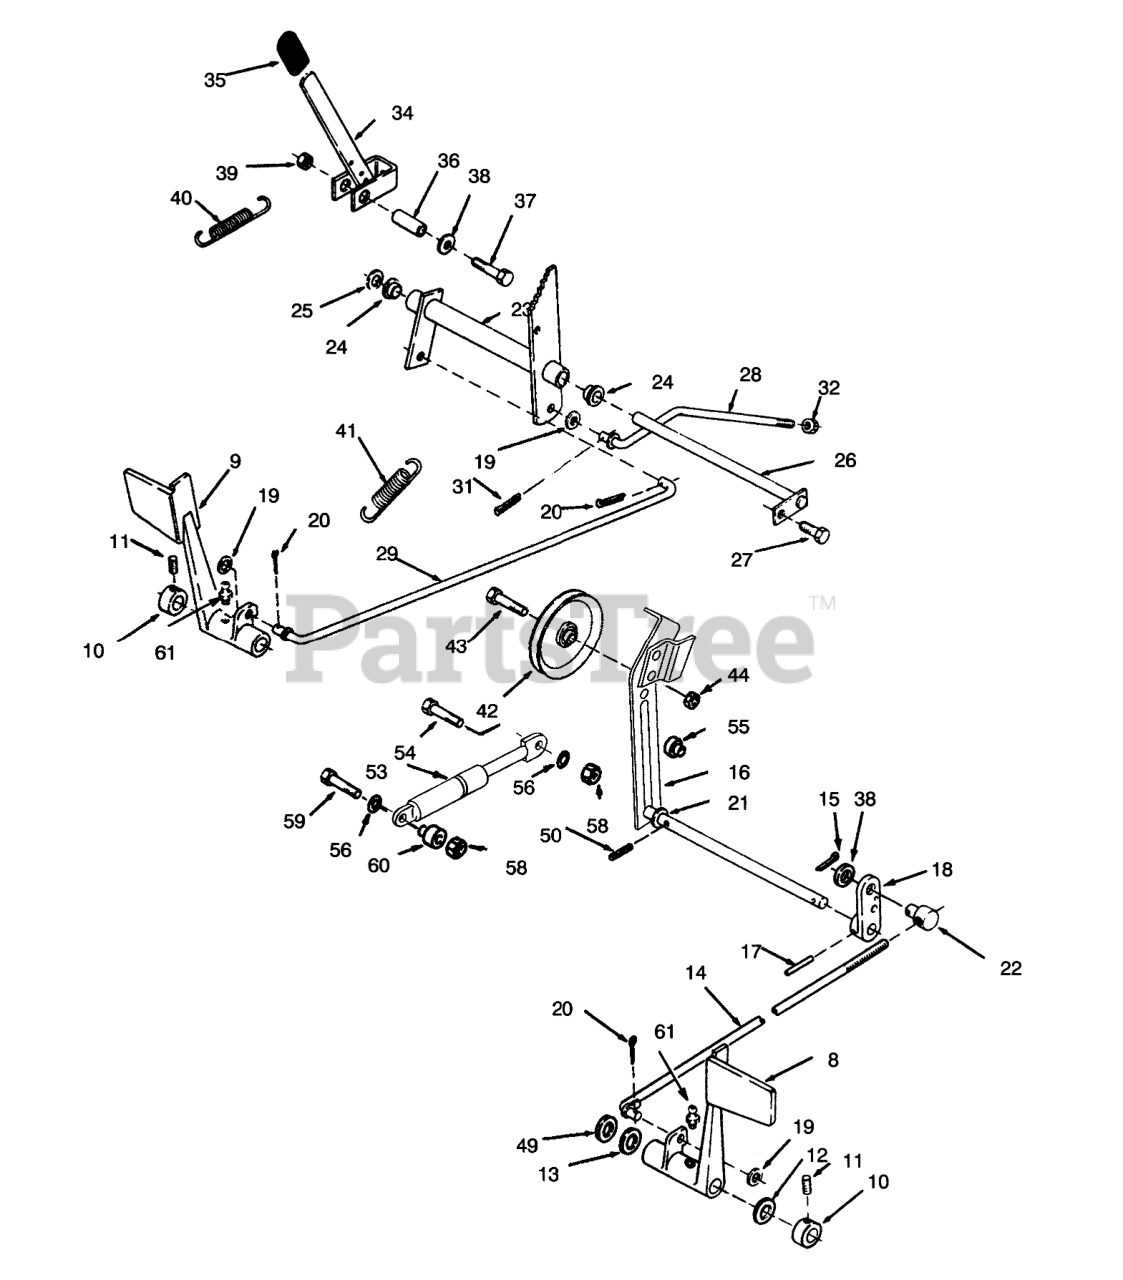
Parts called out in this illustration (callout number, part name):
8	PEDAL-CLUTCH R
9	Pedal-Brake
10	COLLAR
11	SCREW-HSH
12	WASHER-BOWED
13	WASHER
14	ROD AND GUIDE ASM
15	PIN-COTTER
16	Arm-Clutch Idler
17	PIN-SPIROL
18	Arm-Clutch Rod
19	WASHER-NYLON
20	PIN-COTTER
21	SHIM-WASHER
22	TRUNNION
23	Bellcrank Assy
24	BUSHING-FLANGED
25	WASHER-FLAT
26	ROD ASM
27	SCREW
28	ROD-REAR BRAKE
31	Hairpin Cotter
32	NUT-LOCK, NI
34	ASSY-BRAKE LEVER WAB
35	GRIP
36	SPACER
37	SCREW-HH
38	WASHER-FLAT
39	LOCKNUT-FLANGE
40	SPRING-BRAKE
41	SPRING-EXTENSION
42	PULLEY-IDLER
43	BOLT-SPECIAL HEX
44	NUT-HEX
49	Washer
50	PIN-SPIROL
53	ASS'Y-GAS SPRING
54	Capscrew
55	SPACER-SHOULDER-.200
56	WASHER-FLAT
58	NUT-LOCK, NI
59	SCREW-HH
60	SPACER-SHOULDER-.400
61	FITTING-GREASE
